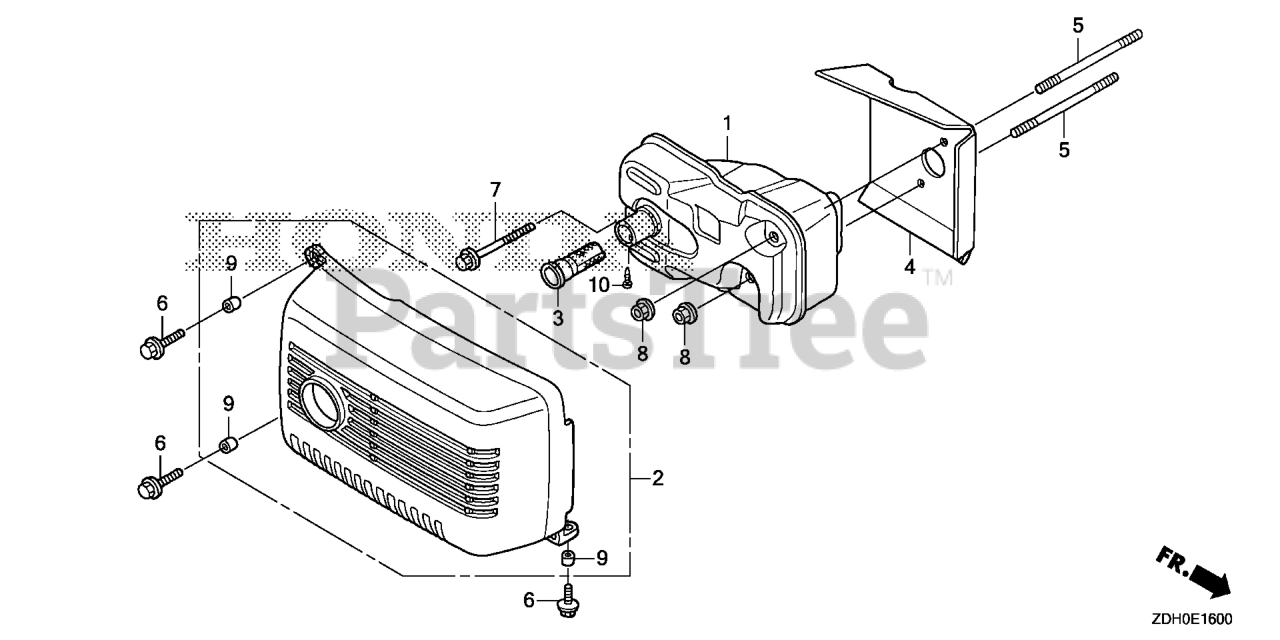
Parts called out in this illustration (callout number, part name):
2	PROTECTOR, MUFFLER
3	ARRESTER, SPARK
4	GUIDE, AIR
5	BOLT 2, STUD (5X55)
6	BOLT, FLANGE (5X16)
7	BOLT, FLANGE (5X35)
8	NUT, SELF-LOCK (5MM)
9	COLLAR, TOP COVER
10	SCREW, TAPPING (4X8)
